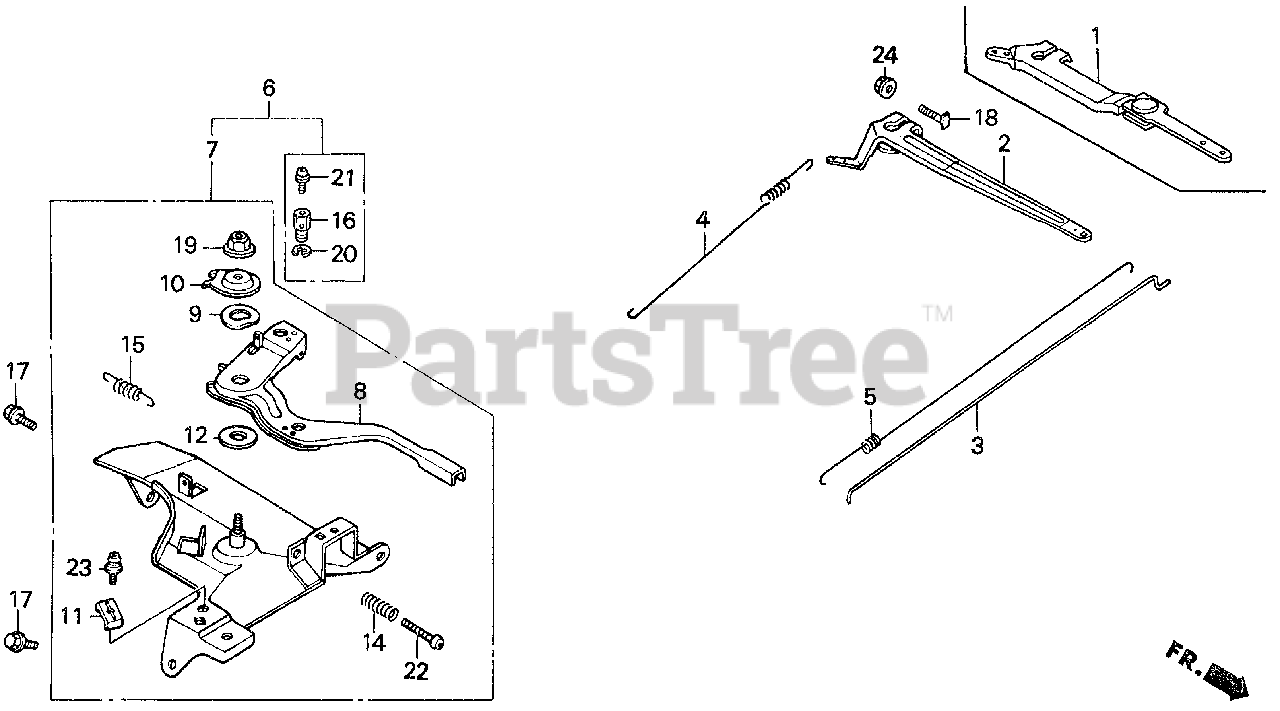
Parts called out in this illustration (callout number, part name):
2	ARM, GOVERNOR
3	ROD, GOVERNOR
4	SPRING, GOVERNOR
5	SPRING, THROTTLE RETURN
6	CONTROL ASSY. (REMOTE)
8	LEVER, CONTROL
9	SPRING, LEVER
10	WASHER, CONTROL LEVER
11	HOLDER, CABLE
12	SPACER, CONTROL LEVER
14	SPRING, CONTROL ADJUSTING
15	SPRING, CABLE RETURN
16	HOLDER, WIRE
17	BOLT, FLANGE (6X12) (CT200)
18	BOLT, GOVERNOR ARM
19	NUT, SELF-LOCK (6MM)
20	CIRCLIP (5MM)
21	SCREW, PAN (4X6)
22	SCREW, PAN (5X32)
23	SCREW, PAN (5X16)
24	NUT, FLANGE (6MM)
